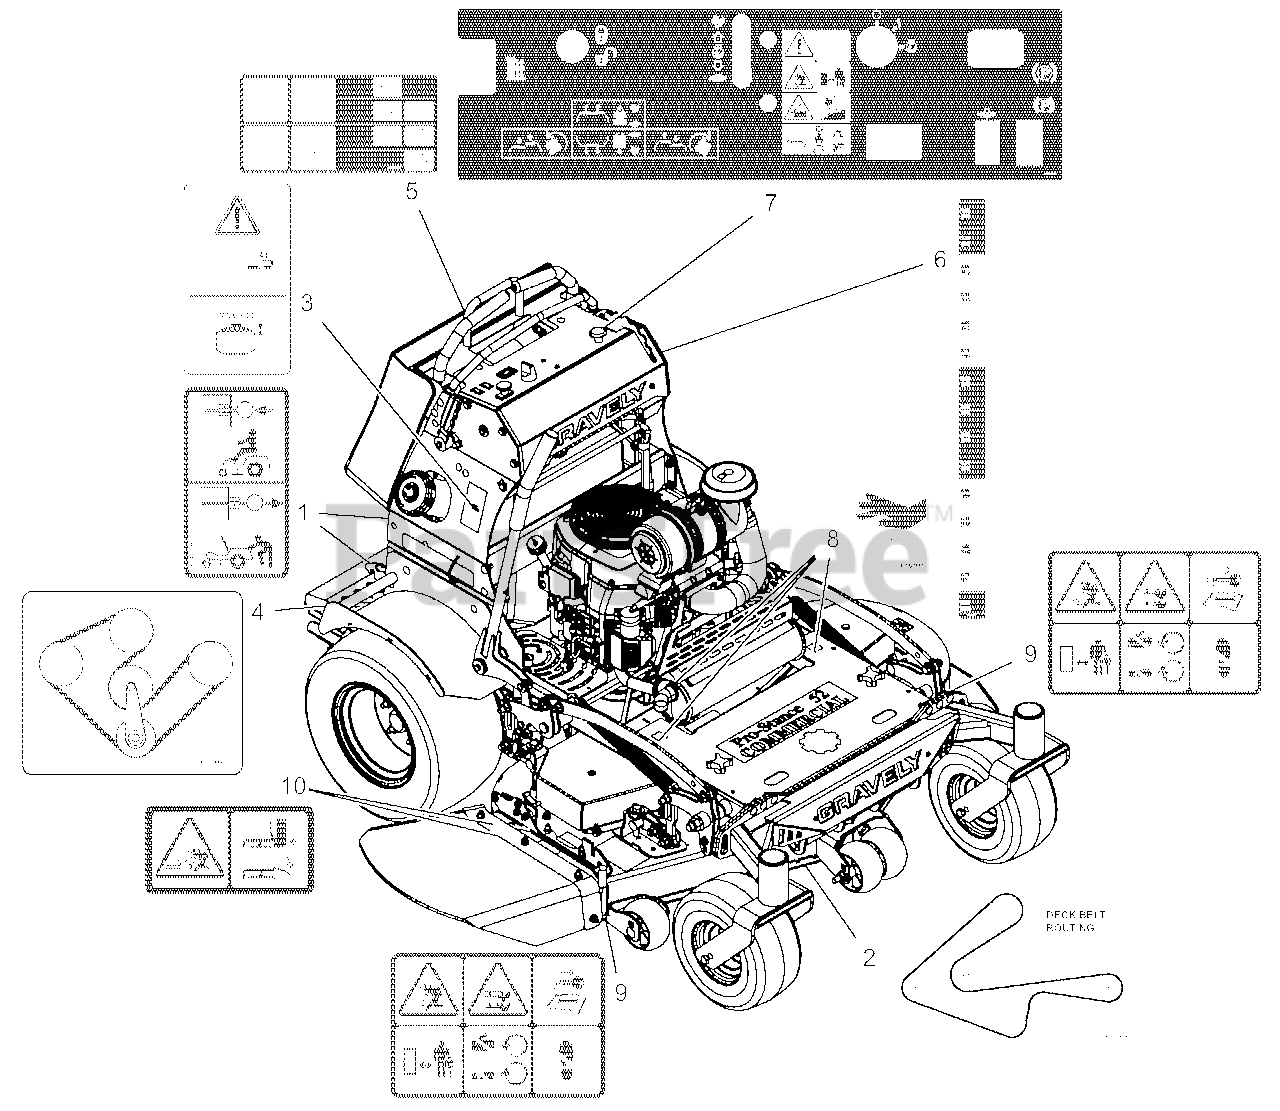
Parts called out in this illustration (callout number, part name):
1	DECAL, TRANSMISSION DISCONNECT
2	DECAL, BELT ROUTING 48/52 REV
3	DECAL, FUEL Warning
4	DECAL, HYDRO BELT (PROSTANCE)
5	DECAL, FUSE BLOCK
6	DECAL, HEIGHT OF CUT - PROSTANCE
7	DECAL, CONTROL PANEL EFI
8	DECAL HOT SURFACE
9	DECAL, SAFETY - MOWER DECK
10	DECAL, SAFETY - DECK GUARDING
